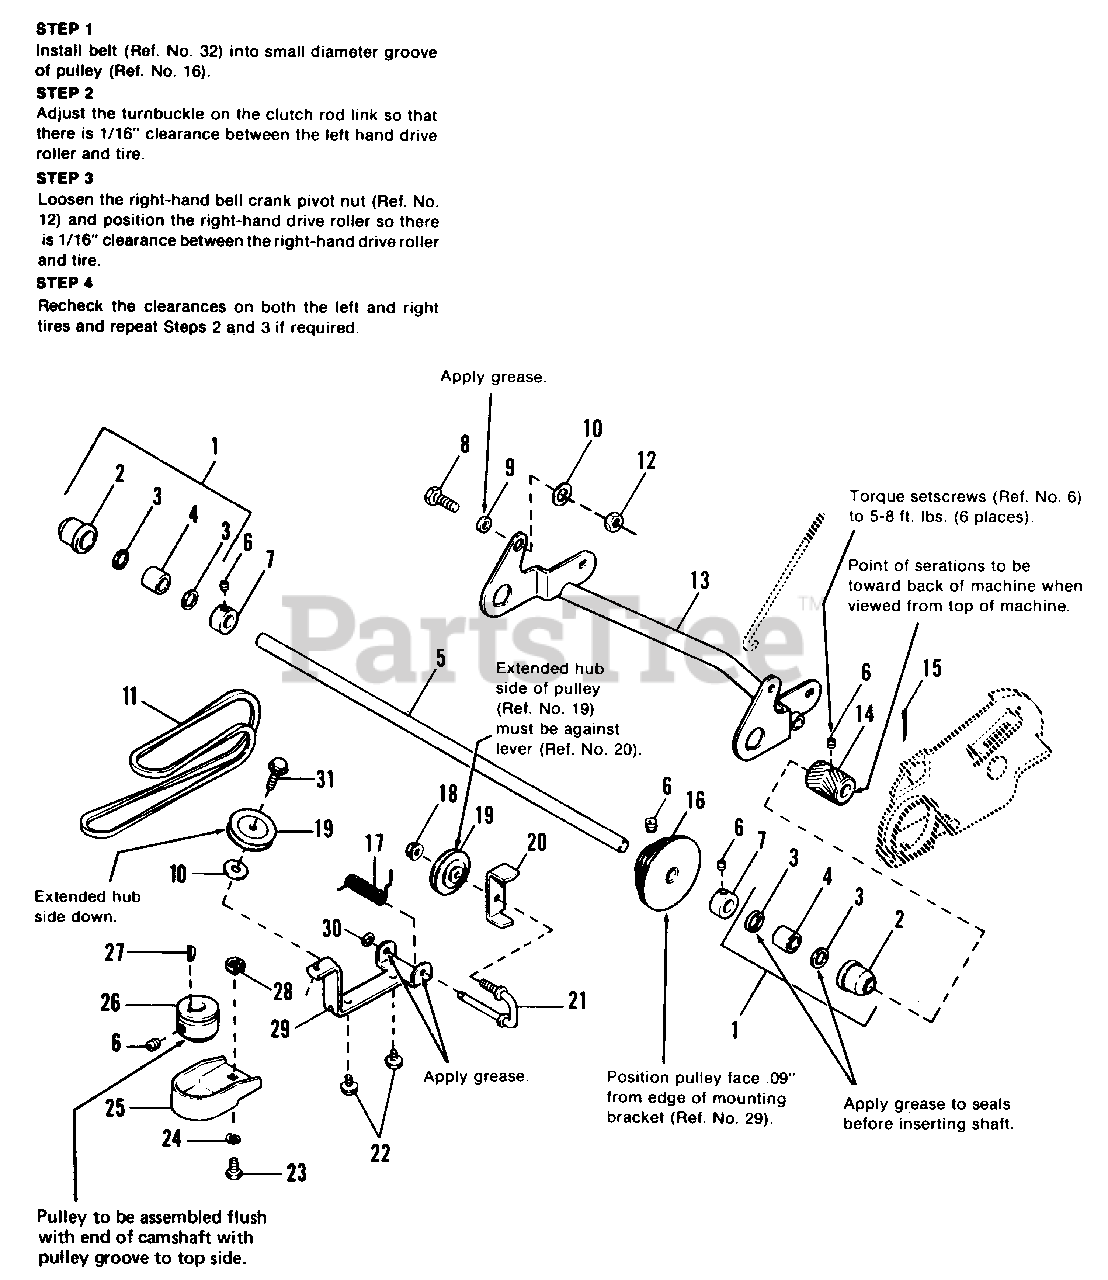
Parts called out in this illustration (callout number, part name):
1	BEARING & RETAINER ASSY.
3	SEAL, Grease
5	SHAFT, Driver
6	SCREW, Set
7	COLLAR, Set
8	CAPSCREW, Hex, 5/16-18 x 1
10	WASHER, Plain, 5/16
12	NUT, Hex, 5/16-18 Lock
13	BELLCRANK ASSY.
14	DRIVER, Wheel
15	PIN, Cotter, 3/32 x 3/4
16	PULLEY, Driven
17	SPRING, ldler
18	LOCKNUT, Flange, 1/4-20
19	PULLEY ASSY.
22	SCREW, Taptite, 1/4-20 x 12
23	CAPSCREW, Hex, 1/4-20 x 5/8
24	LOCKWASHER, 1/4
25	COVER, Pulley
26	PULLEY, Engine
27	KEY, Woodruff, #5
28	NUT, Tinnerman, 1/4-20
29	BRACKET, Idler Support
30	RING, Retaining
31	SCREW, Taptite, 1/4-20 x 1
